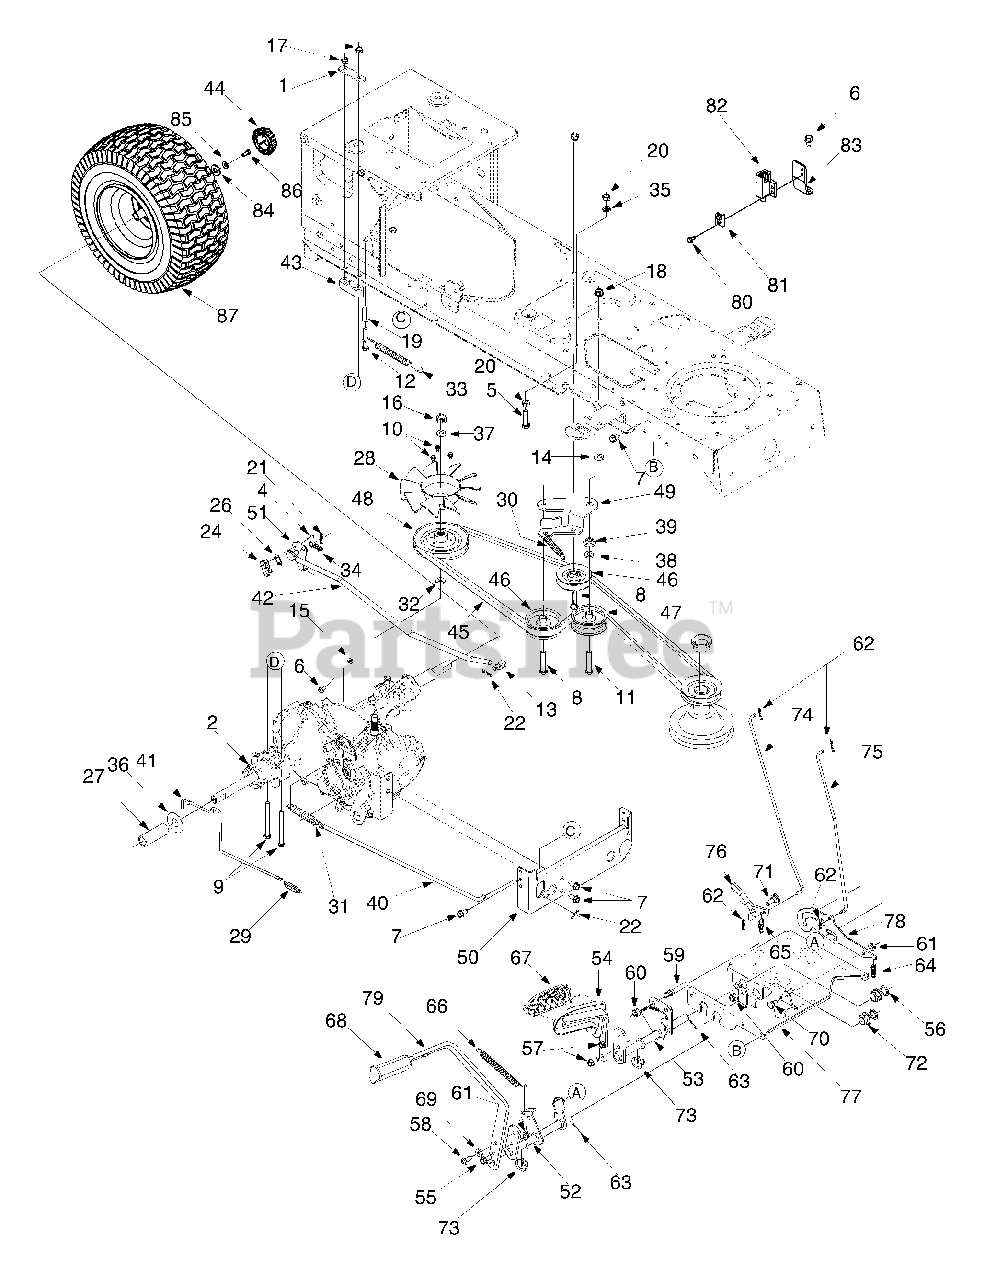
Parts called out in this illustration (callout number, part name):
2	Hydrostatic Transmission
4	AB Screw #8-18 x 0.5
5	Hex Bolt 3/8-16 x 1.5
6	TT Screw 1/4-20 x 0.5
7	AB Screw 5/16-12 x 0.75
8	TT Sems Screw 3/8-16 x 1.250
9	Hex Bolt 5/16-18 x 3.5
10	Carriage Screw
11	Hex Bolt 3/8-16 x 2.25
12	Screw, 1/4-20 x 1.250
13	Ferrule
14	Flat Washer,.38 x 1.38 x.125
15	Hex Lock Nut 1/4-20
16	Hex Nut, 1/2-20
17	Flange Lock Nut, 5/16-18
18	Flanged Lock Nut 3/8-16
19	Spacer,.260 x.372 x 1.030 Lg
20	Hex Nut 3/8-16
26	Insulator Nut Plate
27	Sleve, 0.758 x 0.821 x 1.5
28	Blade Fan
29	Extension Spring
30	Extension Spring
31	Extension Spring
33	Extension Spring
34	Extension Spring
39	Shoulder Spacer
43	Transaxle Spacer
44	Hub Cap
45	V Belt, A x 78" Lg
46	Idler Pulley
47	Flat Idler Pulley
55	TT Screw 5/16-18 x 0.875
56	Flat Washer,.64 x 1.24 x.06
57	LD Screw 5/16-18 x 0.75
58	TT Screw 5/16-18 x 0.75
60	Flange Lock Nut, 3/8-16
61	Flange Lock Nut, 5/16-18
64	Compression Spring
65	Extension Spring
66	Extension Spring
67	Control Pedal
68	Brake Control Pedal
69	Flat Washer
70	Shoulder Screw
71	Shoulder Screw
72	Hex Flange Bearing
73	Hex Flange Bearing
74	Brake Lock Control Rod
75	Cruise Control Rod
76	Cruise Latch
78	Lockout Bracket
81	Switch Plate
82	Interlock Switch
85	Bell Washer,.340 x.872 x.060
86	Screw, 5/16-24 x.750
